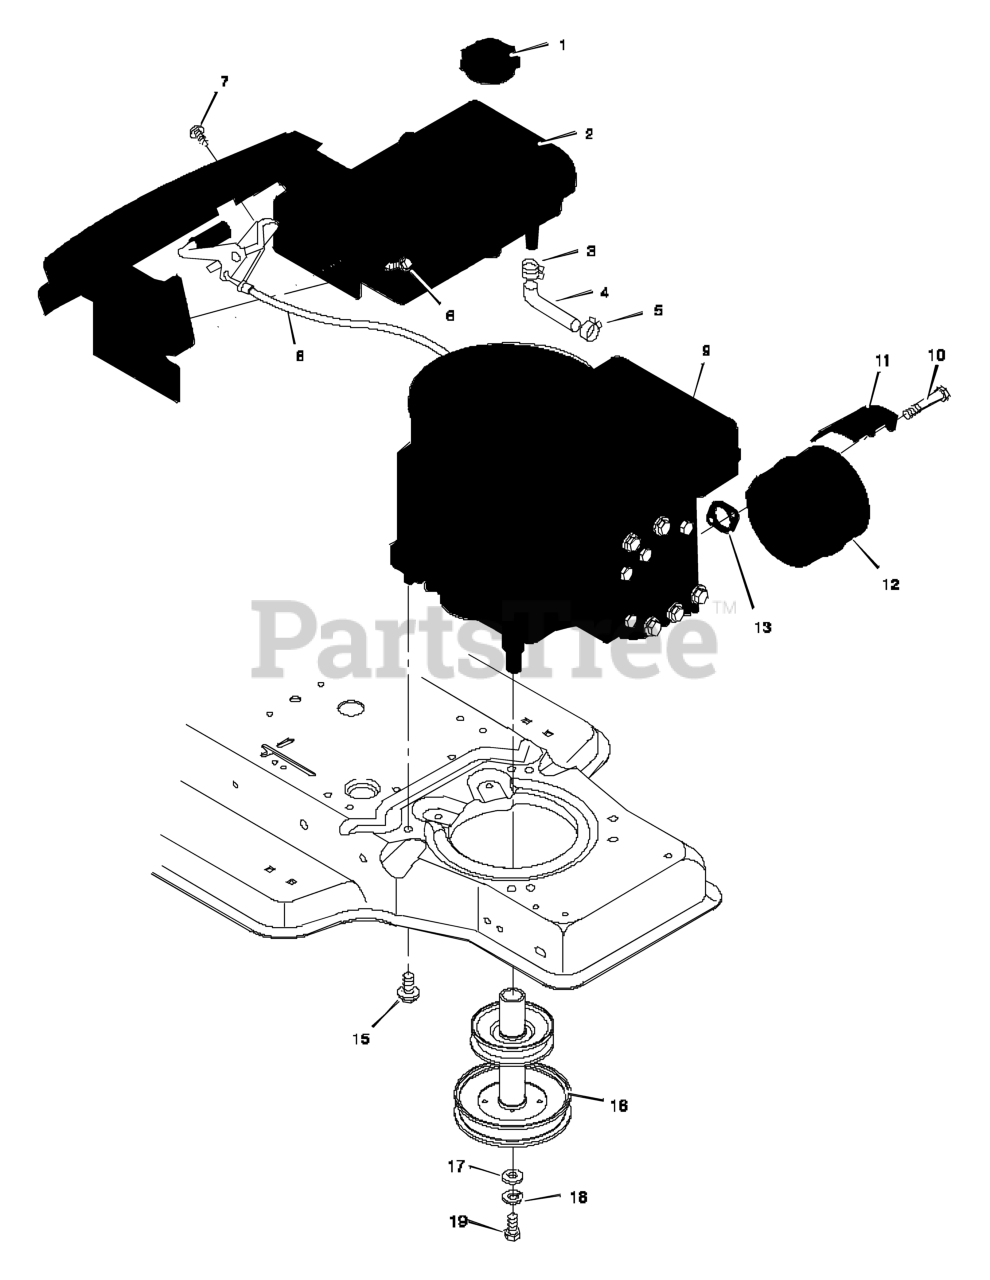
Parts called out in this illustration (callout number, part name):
1	Fuel Cap
2	Fuel Tank
3	Hose Clamp
4	Fuel Line
5	Hose Clamp
8	Throttle Control
9	Engine
11	Shield, Heat
12	Muffler
13	GASKET, Exhaust
15	Bolt, Engine Mount
16	Pulley, Stack
18	Lockwasher
19	Bolt, Hex
